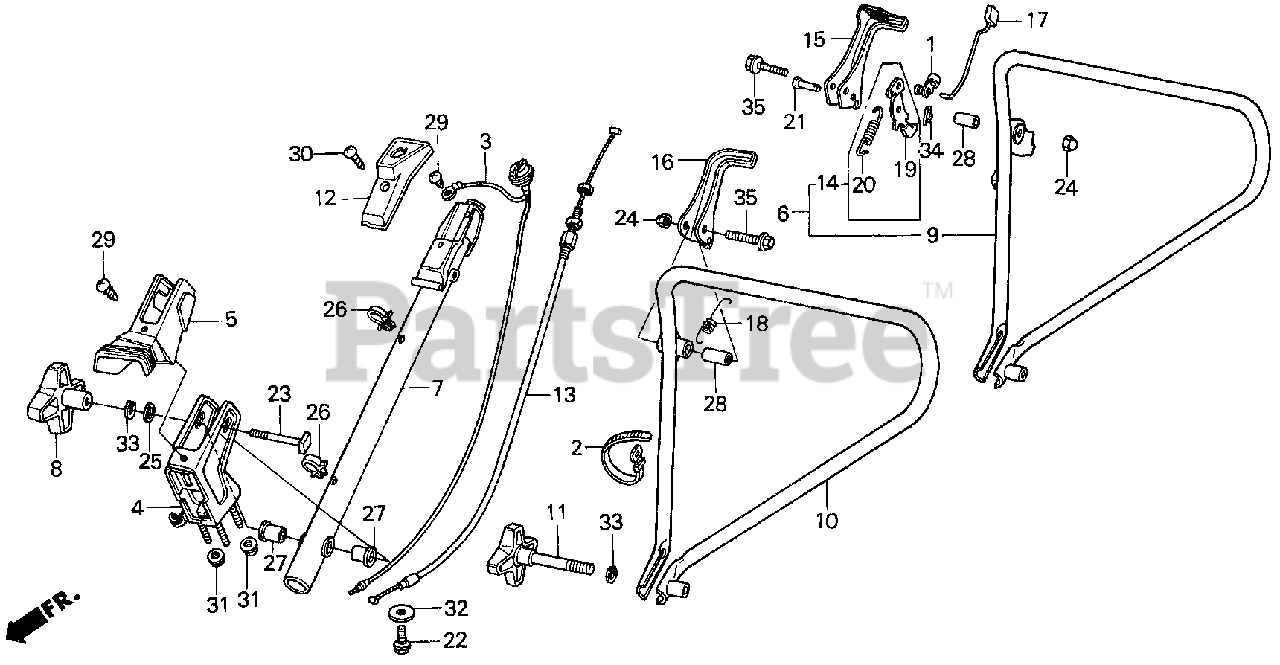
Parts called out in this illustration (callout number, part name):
1	JOINT, ROD
2	BAND B1, WIRE
3	SWITCH, ENGINE STOP
4	COLUMN, HANDLE (NOT AVAILABLE)
5	COVER, HANDLE COLUMN (NOT AVAILABLE)
6	HANDLE SET (UPPER) (NOT AVAILABLE)
7	HANDLE (LOWER) (NOT AVAILABLE)
8	GRIP, HANDLE (LOWER)
9	HANDLE SET (UPPER)
11	GRIP, HANDLE JOINT
12	COVER, CONTROL (NOT AVAILABLE)
13	CABLE, ROTO-STOP
14	LEVER SET, LOCK
15	LEVER, ROTO-STOP (NOT AVAILABLE)
17	ROD, RATCHET PUSH (NOT AVAILABLE)
18	SPRING, LEVER (NOT AVAILABLE)
19	LEVER SET, LOCK
19	LEVER, LOCK
20	SPRING, RATCHET RETURN
21	PIN, SEAT HINGE
22	BOLT, FLANGE (6X20) (CT200)
23	BOLT, HANDLE JOINT (NOT AVAILABLE)
24	NUT, CAP (6MM)
25	WASHER, SEAL (8MM)
26	CLIP B, CABLE (9MM BLACK)
27	COLLAR, DISTANCE (NOT AVAILABLE)
28	COLLAR, LEVER (NOT AVAILABLE)
29	SCREW, TAPPING (5X8)
30	SCREW, TAPPING (5X12)
31	NUT, FLANGE (8MM)
32	WASHER, PLAIN (6MM)
33	WASHER, SPRING (8MM)
34	PIN, LOCK (6MM)
35	BOLT, FLANGE (6X32)
